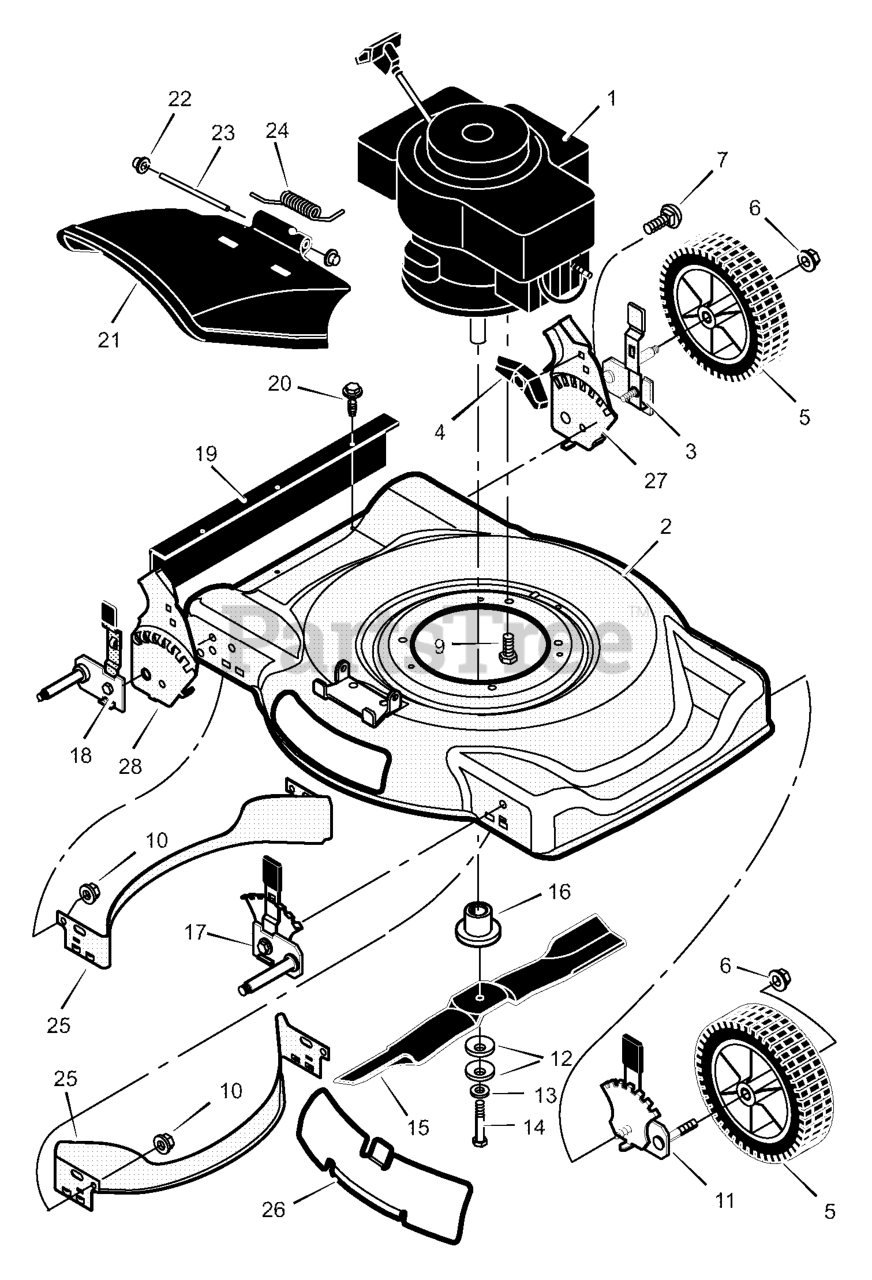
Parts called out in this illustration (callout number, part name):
1	Engine
2	Housing
3	Height Adjuster, Left Rear
5	Wheel and Tire
6	Locknut, Flange
7	Bolt, Carriage
9	Bolt, Engine
10	Nut
11	Height Adjuster, Left Front
12	Washer, Belleville
14	Bolt, Hex
15	Blade, Side Discharge
15	Blade, Mulcher
16	Adapter, Blade
17	Height Adjuster, Right Front
18	Height Adjuster, Right Rear
19	Guard, Rear
21	Deflector, Chute
22	Push-On Cap
23	Pin, Pivot
25	Baffle -
26	Plate, Mulcher
27	Bracket, Left Handle
28	Bracket, Right Handle
